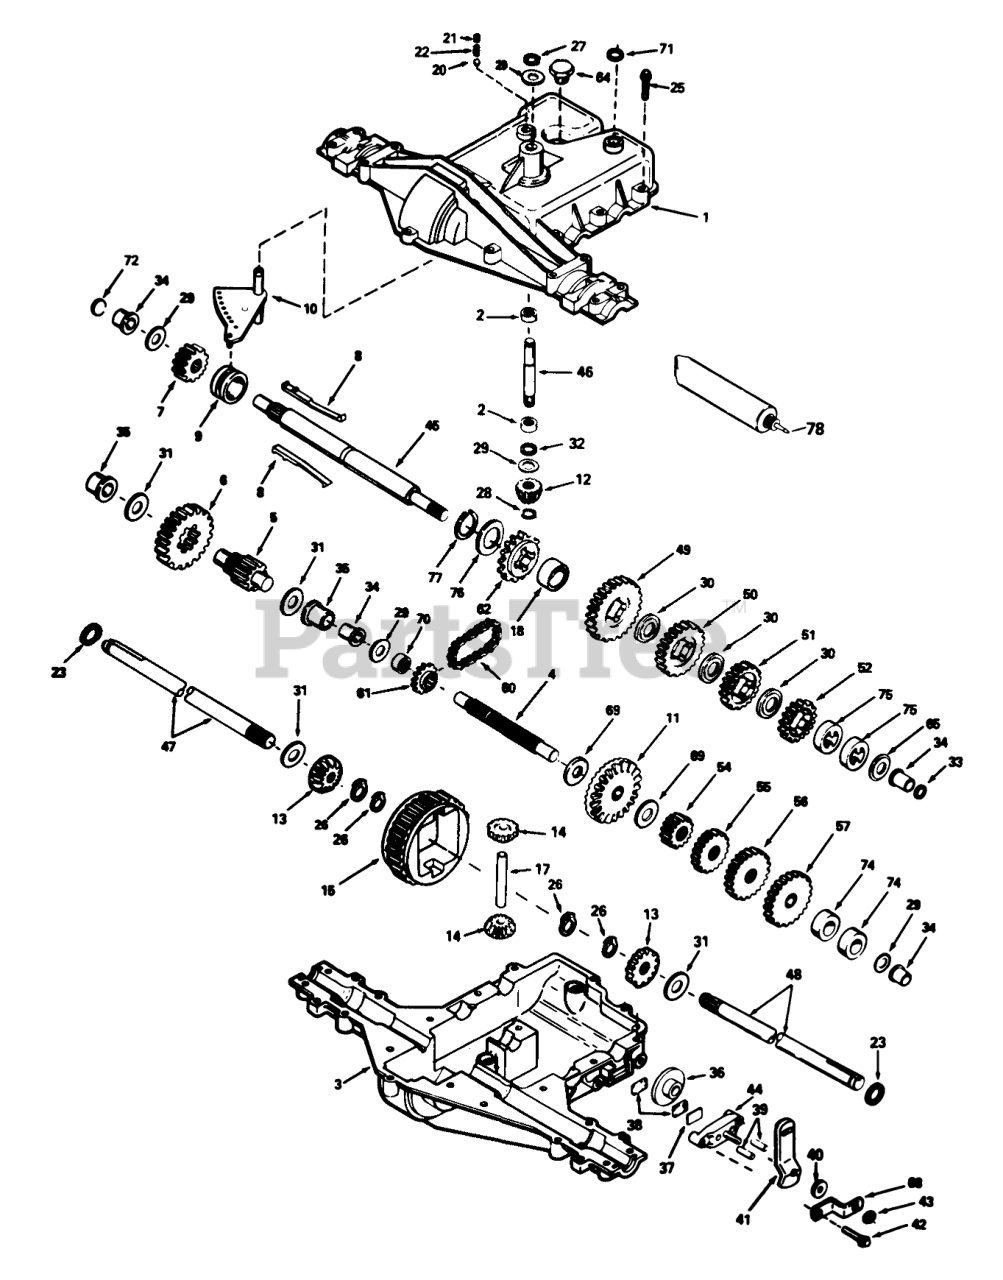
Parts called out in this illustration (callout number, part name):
1	Cover-Transaxle
2	Bearing-Needle
3	Case-Transaxle
4	Shaft-Counter
5	Output Shaft & Pinion Assy.
6	Gear-Output
7	Gear-Spur 15 Teeth
8	Key-Shifter
9	Shift Collar
10	Shift Rod & Fork Assy.
11	Gear-Bevel (42 teeth)
12	Bevel Pinion-Input
13	Gear Bevel
14	Gear Pinion
15	Gear-Ring
16	Drive Pin
18	Spacer
20	Ball-Steel
21	Screw-Set
22	Spring
23	Ring-Seal
25	Ring Set (.020 O S)
26	Retaining Ring (pkg of 2)
27	Ring-Snap
28	Ring-Retainer
29	Washer
30	Washer
31	Washer
32	O Ring
33	Ring-Square Cut
34	Bushing-Flange
35	Bushing-Flanged
37	Brake Pad Plate
38	Brake Pad
39	Dowel Pin
40	Washer
41	Lever-Brake
42	Ring Set (.020 O S)
43	Locknut
44	Nozzle-Carburetor
45	Shaft-Brake (4-keyed)
46	Shaft-Input
47	Axle (11-5/8" long)
48	Axle (16-1/4" long)
49	Gear-Spur (37 teeth)
50	Gear-Spur, 35 Teeth
51	Gear-Spur, 30 Teeth
52	Gear-Spur, 25 Teeth
53	Gear-Spur 20 teeth
54	Gear-Spur (12 teeth)
55	Gear-Spur, 15 Teeth
56	Gear-Spur, 20 Teeth
57	Gear-Spur, 25 Teeth
58	Gear-Spur (30 teeth)
60	Chain-Roller
61	Sprocket 10t
62	Sprocket (14 teeth)
65	Washer
68	Bracket
69	Washer
70	Spacer
71	Cut Seal-Square
74	Spacer
75	Spacer
76	Washer
77	Ring-Retaining
78	Grease 32 Oz
